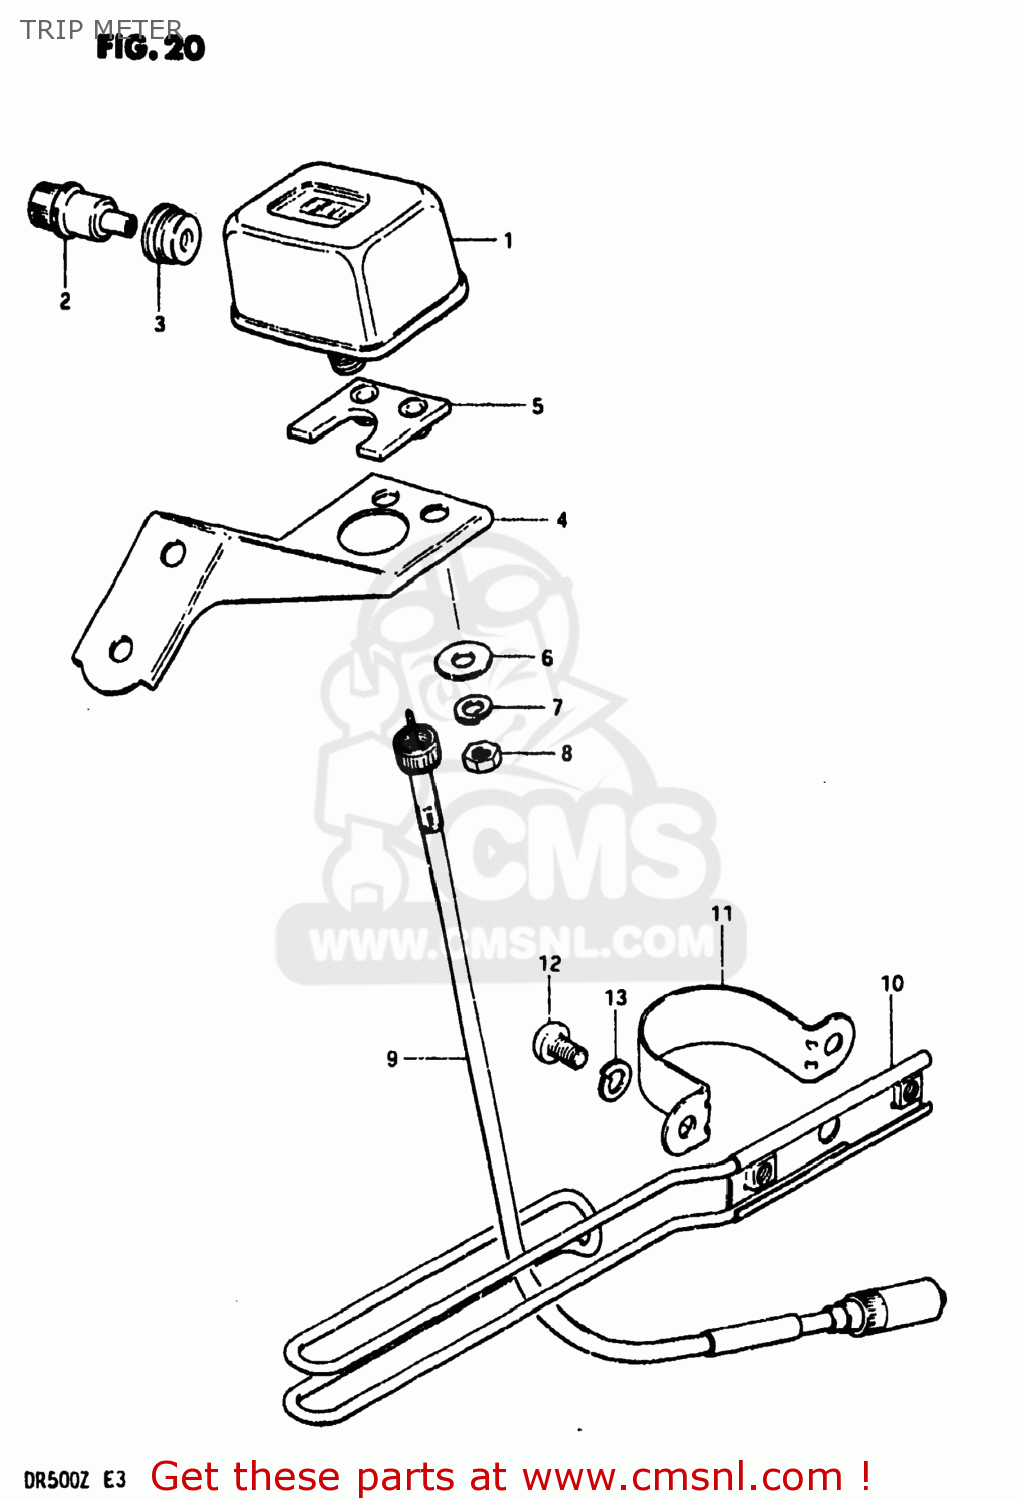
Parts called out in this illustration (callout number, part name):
1	TRIP METER
2	KNOB,TRIP METER
3	COVER,TRIPMETER KNOB
4	BRACKET,TRIPMETER
5	CUSHION,TRIPMETER
6	WASHER,METER
7	LOCK WASHER
8	NUT
9	CABLE ASSEMBLY,SPEEDOMETER
10	CLAMP,SPEEDOMETER CABLE
11	CLAMP
12	SCREW 6X12
13	LOCK WASHER
